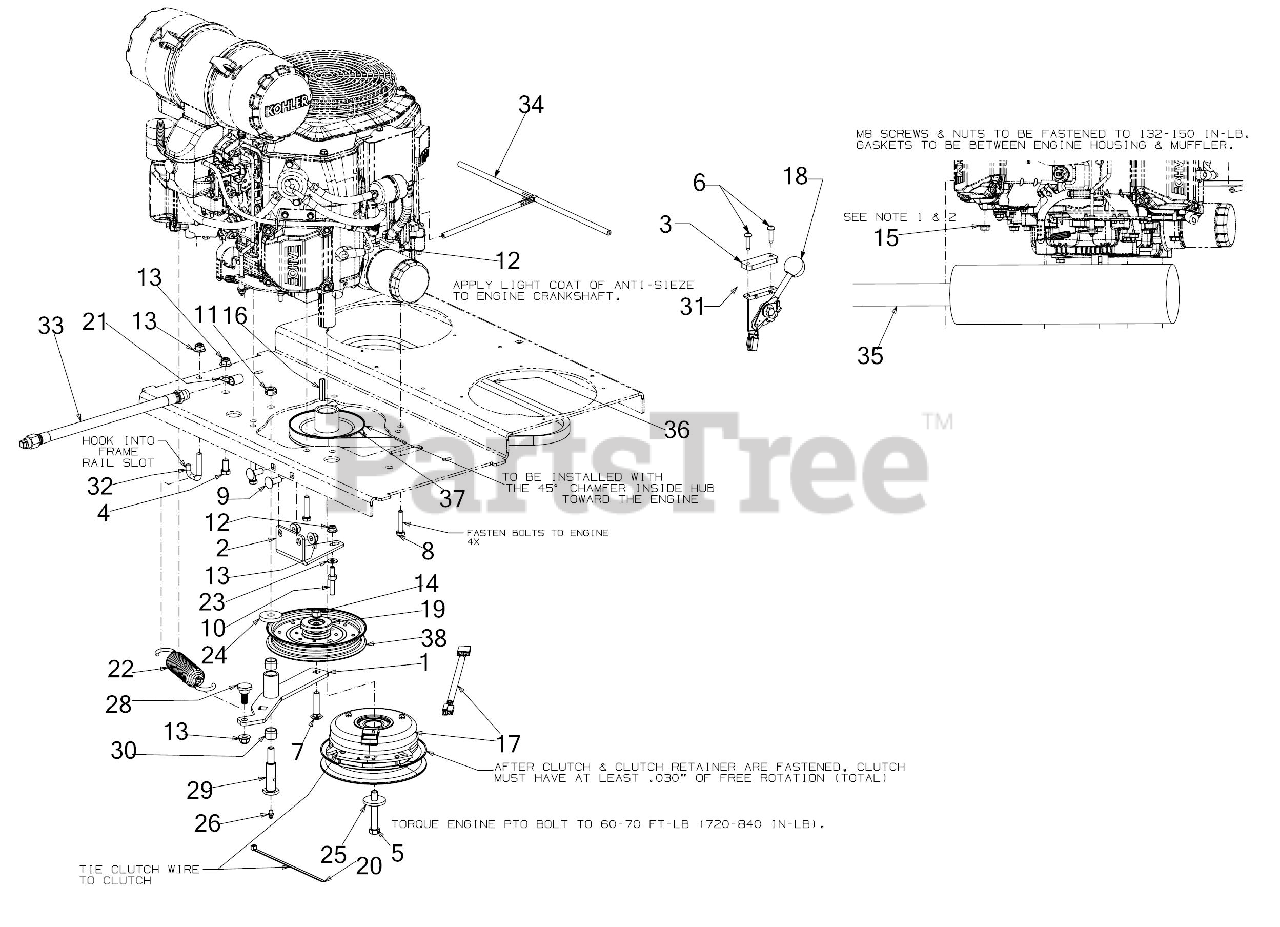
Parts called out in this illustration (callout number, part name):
1	TRANSMISSION IDLER BRACKET
2	RETAINER BRACKET
3	THROTTLE CABLE SPACER
4	HEX SCREW 3/8-16 x .75
5	SCREW 7/16-20:2.75 GR5
6	SCREW 1/4-20 x 1.0
7	CARRIAGE BOLT 3/8-16 x 1.75 GR5
8	SCREW 5/16-18 x 1.5 LG
9	CARRIAGE BOLT 3/8-16 x 1.00 GR5
12	FLANGE LOCK NUT 5/16-18
14	HEX LOCK NUT
15	HEX FLANGE NUT
16	SQUARE KEY 1/4 x 1.50
17	ELECTRIC PTO CLUTCH
19	PULLEY CAP
20	7" CABLE TIE
21	J TYPE CLIP
22	EXTENSION SPRING W/HOOK
23	FLAT WASHER
24	FLAT WASHER 47 x 1.50 x .225
25	FLAT WASHER .45 x 1.5 x .172 HT
26	GREASE FITTING
28	SHOULDER SCREW .625 x .302 x 3/8-16
29	SHOULDER BOLT 7/16-14
30	SLEEVE BEARING
31	THROTTLE CABLE 59"
32	ROD SPRING HOOK
33	OIL DRAIN HOSE
34	ROLLOVER VENT HOSE ASSEMBLY
35	MUFFLER (KOHLER COMMAND)
36	TRANSMISSION BELT 61.5
37	DRIVE PULLEY
38	IDLER PULLEY
